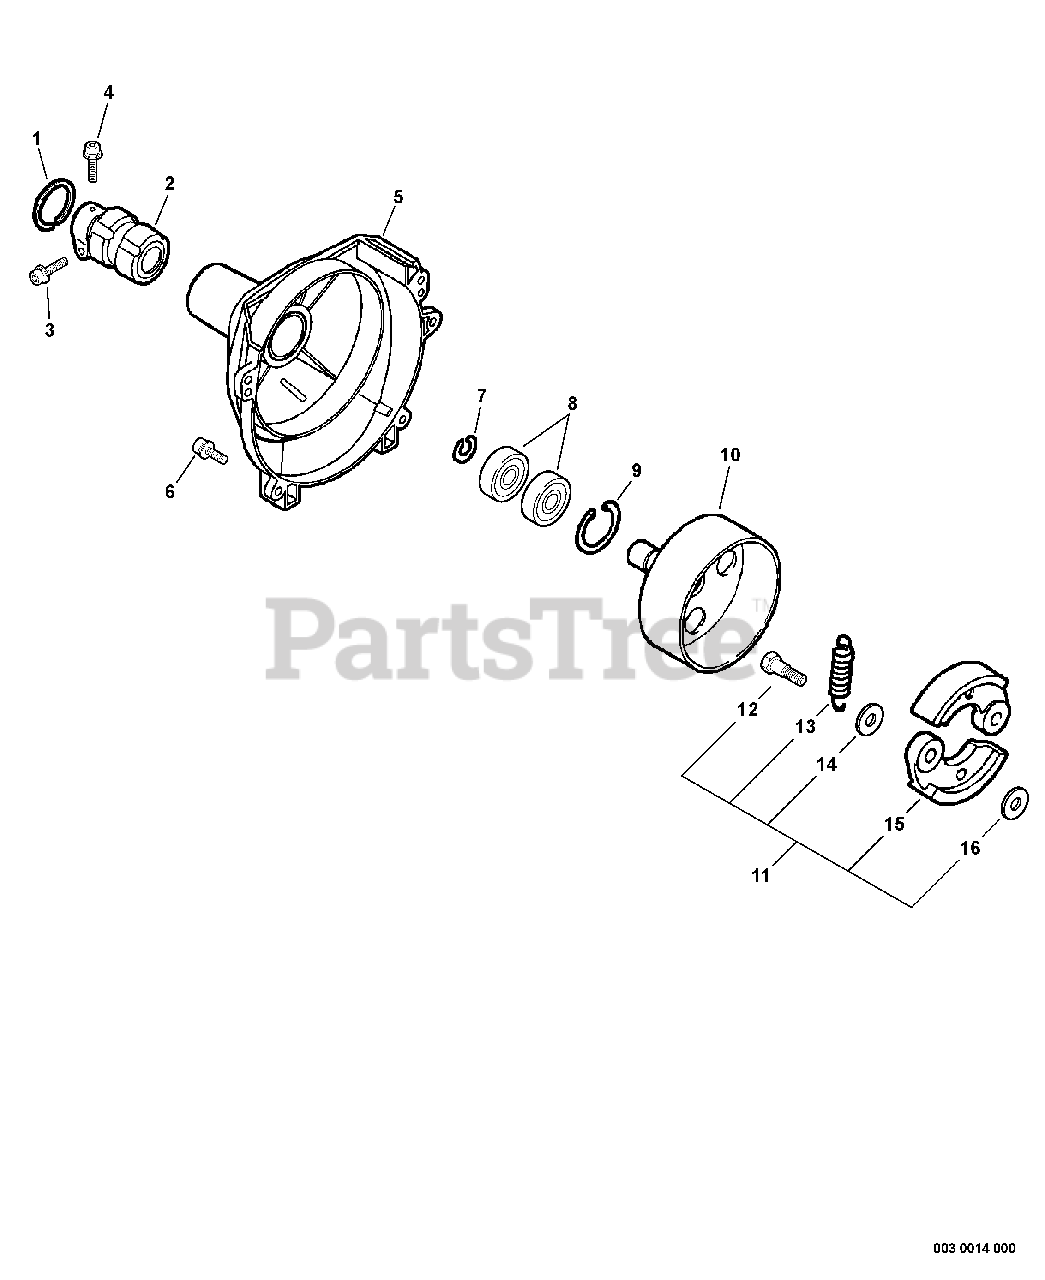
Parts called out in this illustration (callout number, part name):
1	RING, RETAINING - 45
2	CUSHION
3	SCREW - 5X28
4	SCREW - 5X12
5	CASE, FAN
6	SCREW - 5X20
7	RING, RETAINING - 12
8	BEARING, BALL - 6001
9	RING, RETAINING - 28
10	DRUM, CLUTCH
11	CLUTCH ASSY
12	BOLT, CLUTCH
14	WASHER - SPRING
15	SHOE, CLUTCH
